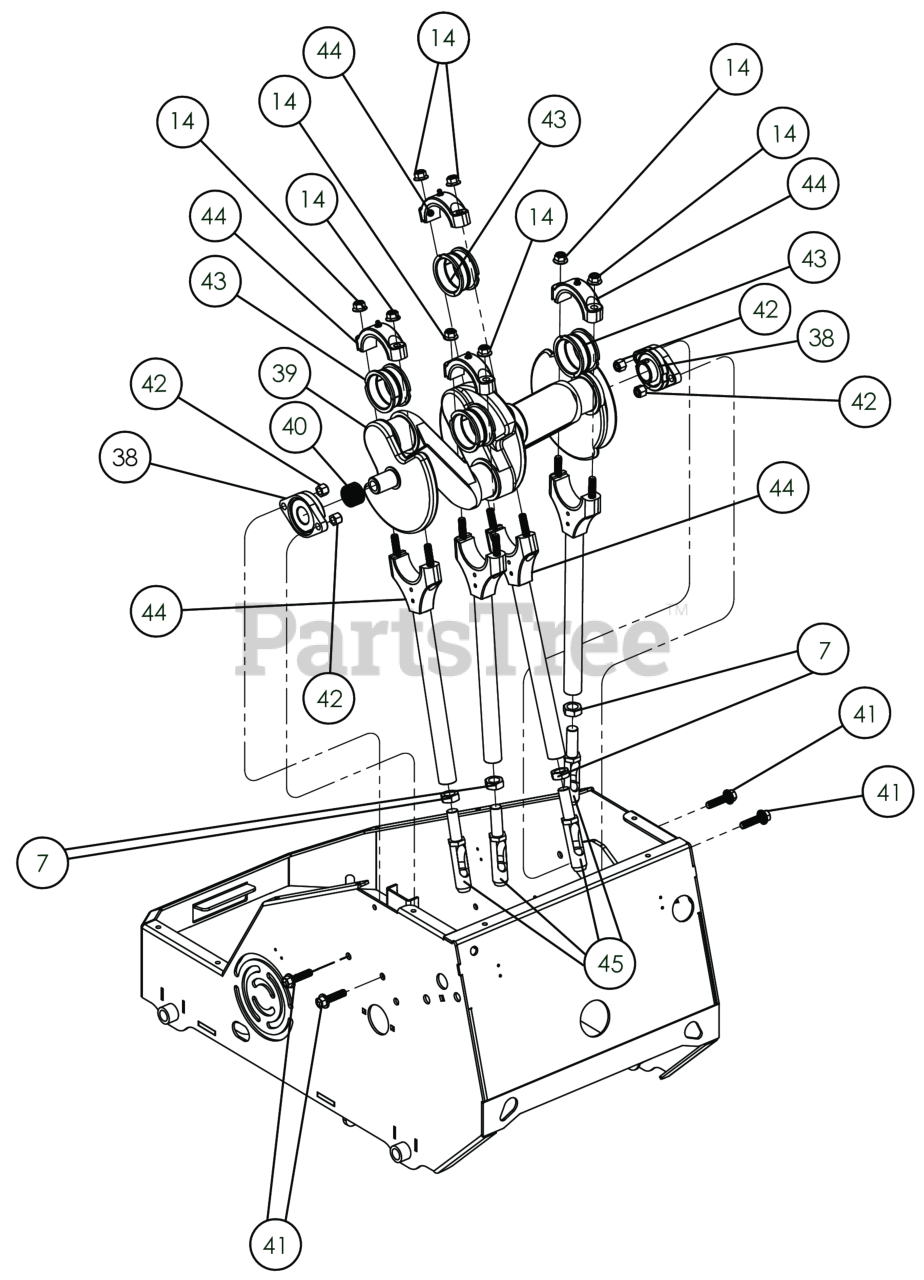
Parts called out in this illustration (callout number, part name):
7	NUT JAM, 5/8-11 ZP
14	NUT-HEX-NYLK, FLG .375"-16 ZP
38	CARTRIDGE BEARING
39	CRANKSHAFT (PL410)
40	SPRING, WAVE 1.000" X .700"
41	SCR-CAP, HSWH .375"-16 X 1.500" G5 ZP
42	NUT LOCK 3/8"-16 HEX
43	BEARING JOURNAL 2" DIA
44	ASM, TINE ROD AND CAP
45	TINE, PLUGR .625"-11 BLACK
